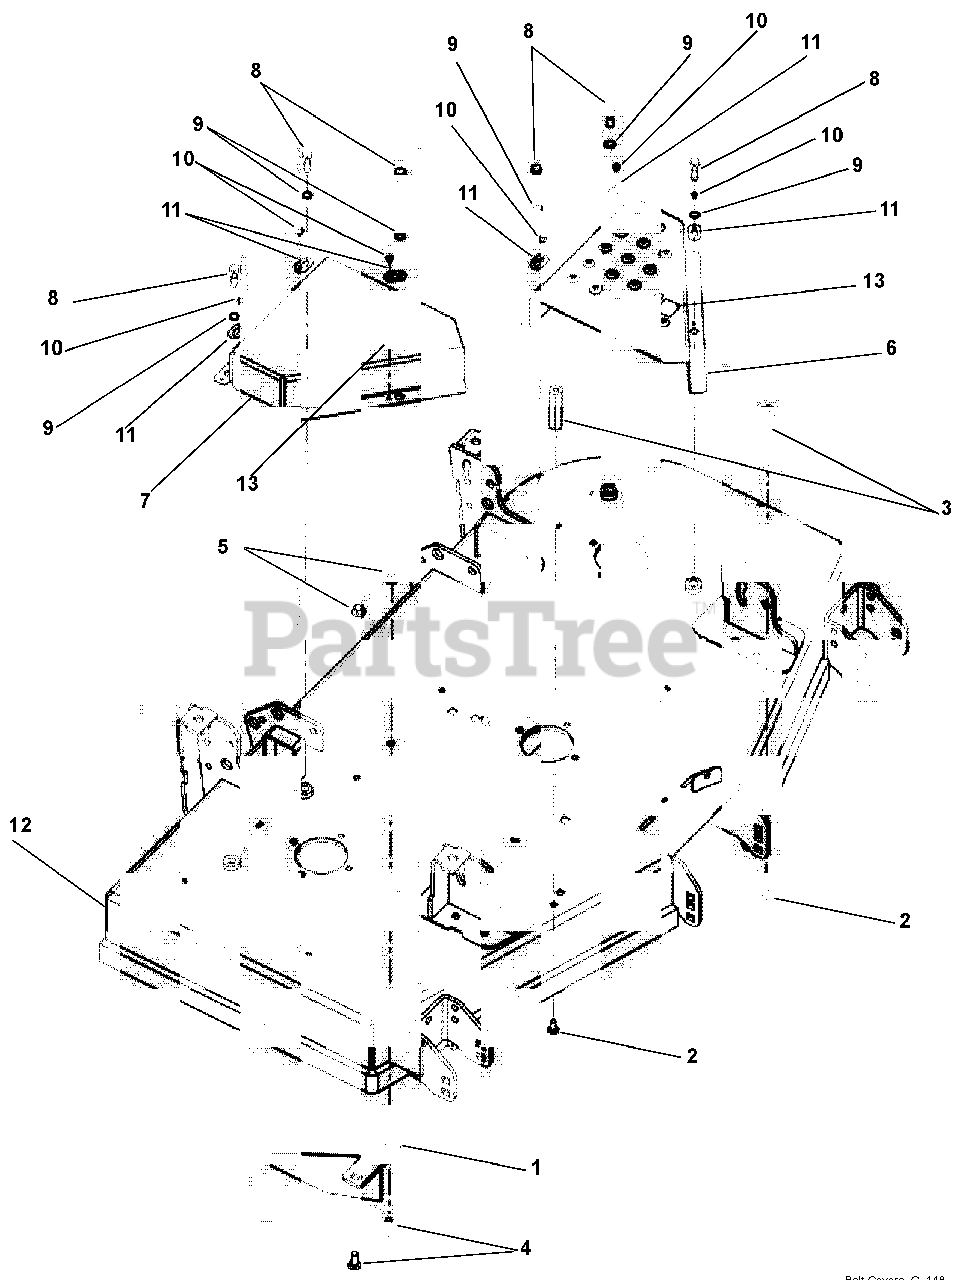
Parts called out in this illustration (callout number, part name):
1	Rear Discharge Deflect Baffle Weldment
2	Bolt, Round Head Square Neck .31 - 18 x .75
3	Nut, Coupling .31 - 18 x 3.00
4	Bolt, Round Head Square Neck .38 - 16 x 1.00
5	Nut, Locking-Nylon-Flange .38 - 16
6	Cover, Left Hand Belt, CE
7	Cover, Right Hand CE Belt
8	Bolt, Hex .38-16 x 1.25
9	Washer, Locking, EXT.391 x .682 x .036
10	Rivet, Pop .187
11	Keeper, Bolt
12	Weldment, 48" PT100 RR DISCH Deck
13	Decal, Pinch Point
